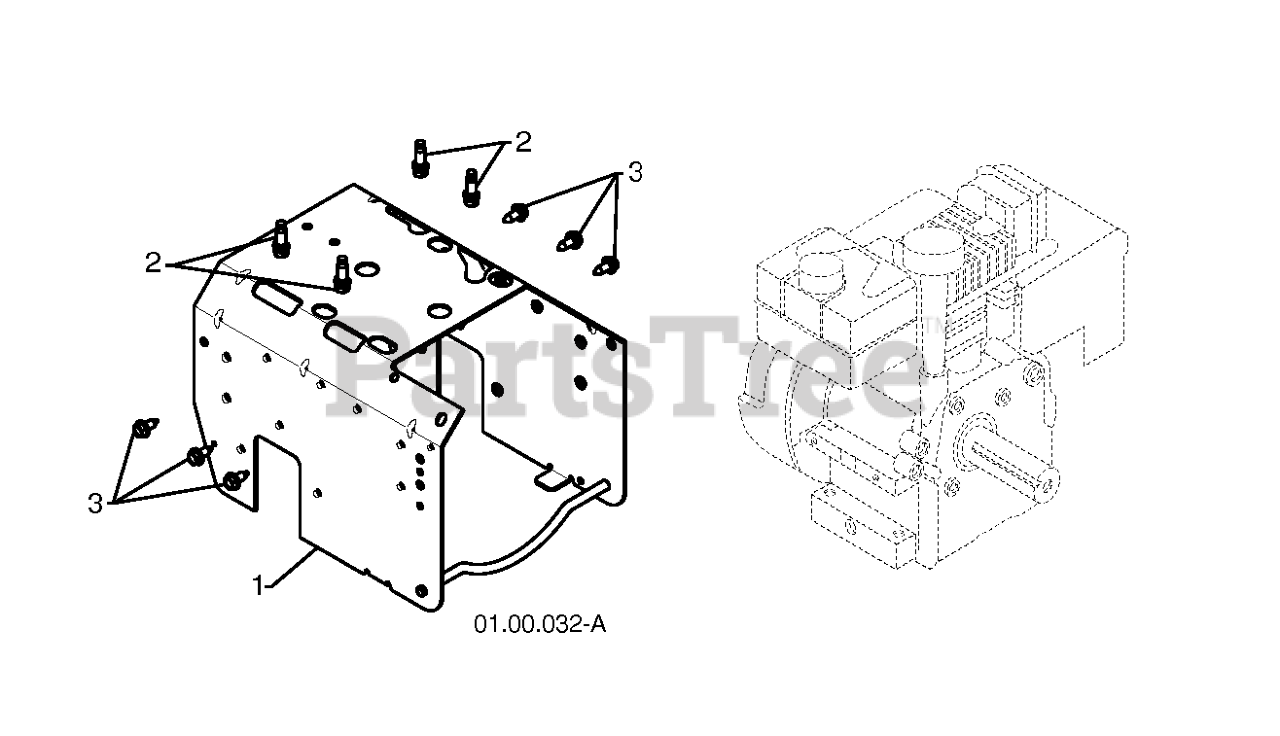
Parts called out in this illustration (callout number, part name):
1	FRAME.WELD.HYDRO.ORANGE
2	BOLT 3/8-16X1-1/8
3	BOLT.HEX.HD.WASHER.5/16-18X.75
